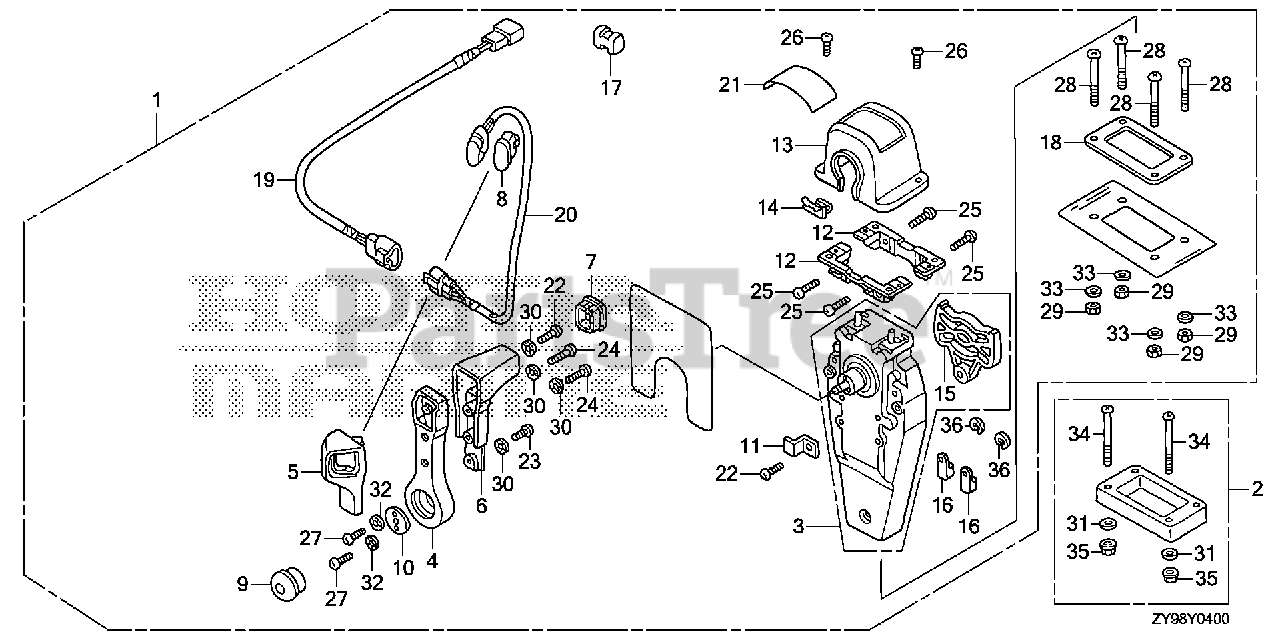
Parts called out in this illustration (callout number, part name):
1	BOX KIT, REMOTE CONTROL (TOP MOUNT SINGLE)(R)
2	SPACER KIT, REMOTE CONTROL BOX (TOP MOUNT SINGLE)
3	HOUSING ASSY., L. (INNER) (TOP MOUNT)
4	HANDLE, REMOTE CONTROL
5	COVER, L. GRIP
6	GRIP, REMOTE CONTROL HANDLE
7	CAP, GRIP
8	CAP, SWITCH
9	BUTTON, THROTTLE
10	PLATE, HANDLE
11	PLATE, CABLE CLAMP
12	BRACKET, REMOTE CONTROL HOUSING
13	HOUSING, REMOTE CONTROL BOX
14	HOUSING, LEAD
15	PLATE, DWELL
16	TERMINAL, CABLE
17	SPACER, CABLE CLAMP
18	GASKET, SINGLE
19	SUB-HARNESS ASSY., POWER TRIM-TILT (A)
20	SWITCH ASSY., POWER TRIM-TILT (A)
21	MARK, REMOTE CONTROL (SINGLE)
22	SCREW, PAN (5X16)
23	SCREW, PAN (5X10)
24	SCREW, PAN (5X20)
25	SCREW, PAN (5X18)
26	SCREW, PAN (4X10)
27	SCREW, PAN (6X18)
28	SCREW, PAN (5X40)
29	NUT, HEX. (5MM)
30	WASHER, LOCK (5MM)
31	WASHER, PLAIN (5MM)
32	WASHER, LOCK (6MM)
33	WASHER, PLAIN (5MM)
34	SCREW, PAN (5X65)
35	NUT, HEX. (5MM)
36	E-RING (6MM)
